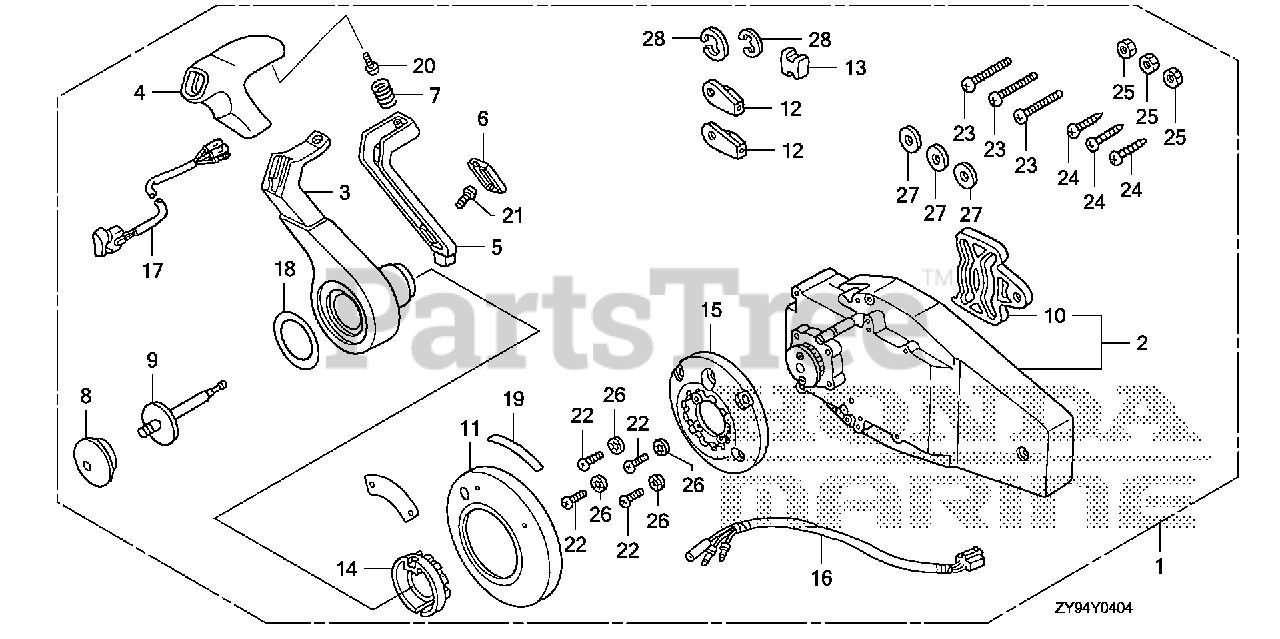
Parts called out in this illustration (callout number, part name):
1	BOX KIT, REMOTE CONTROL (FLUSH MOUNT)(R)
2	HOUSING ASSY., R. (INNER) (FLUSH MOUNT)
3	HANDLE, REMOTE CONTROL
4	COVER, GRIP
5	ARM, NEUTRAL LOCK
6	COVER, LOCK ARM
7	SPRING, NEUTRAL LOCK ARM
8	BUTTON, THROTTLE
9	SHAFT, THROTTLE BUTTON
10	PLATE, DWELL
11	COVER ASSY.
12	TERMINAL, CABLE
13	SPACER, CABLE CLAMP
14	HOLDER, NEUTRAL LOCK
15	BASE
16	SUB-HARNESS ASSY., POWER TRIM-TILT (C)
17	SWITCH ASSY., POWER TRIM-TILT (C)
18	MARK, HANDLE FLUSH MOUNT
19	MARK, FLUSH MOUNT
20	SCREW, PAN (5X16)
21	SCREW, TRUSS (4X12)
22	SCREW, PAN (5X30)
23	SCREW, PAN (6X35)
24	SCREW, TAPPING (6X30)
25	NUT, HEX. (6MM)
26	WASHER, LOCK (5MM)
27	WASHER, PLAIN (6MM)
28	E-RING (6MM)
